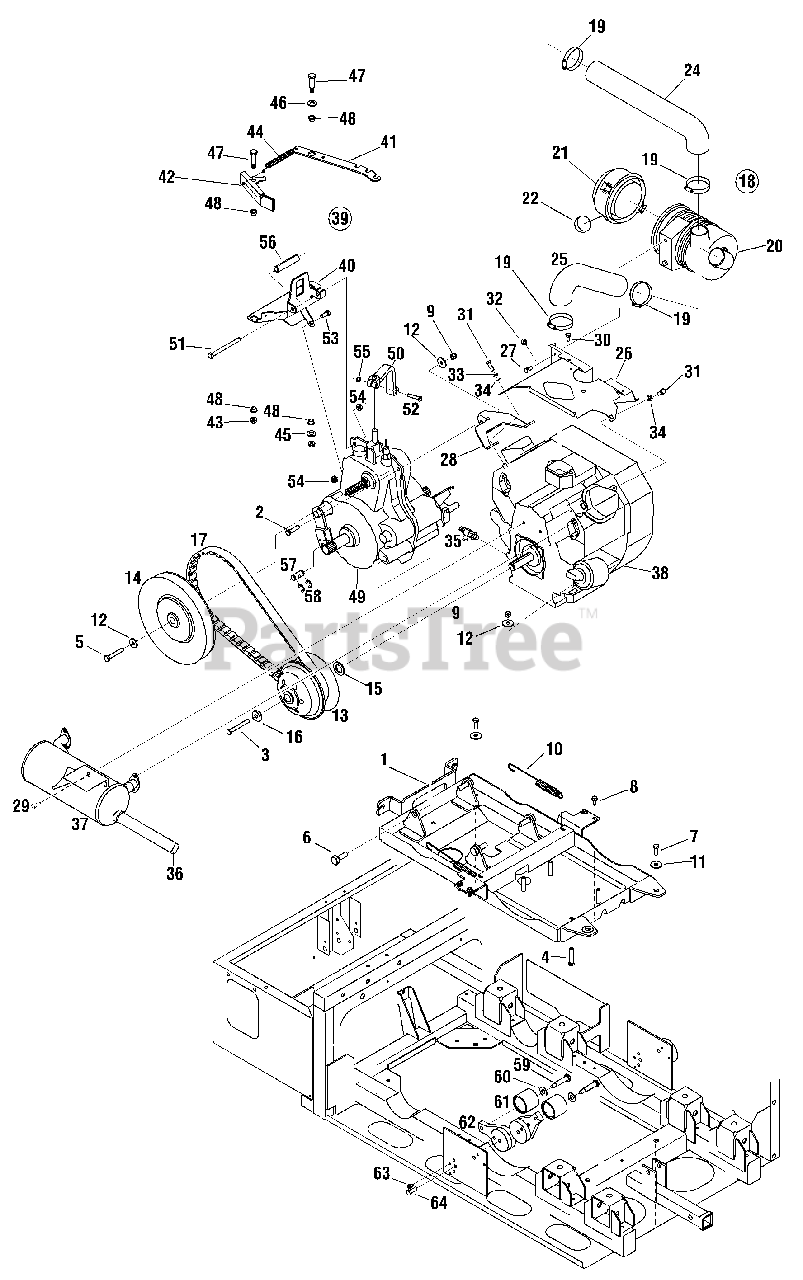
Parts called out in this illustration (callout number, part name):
1	Frame Ass'y, Engine/Trans. Support
2	Hex Screw, 3/8-16 x 1.5, Gr5
3	Hex Screw, 3/8-24 x 3, Gr5
4	Hex Screw, 3/8-16 x 2.00
5	Hex Screw, M10-1.5 x 60mm, Gr8
6	Hex Screw, M16-2 x 40mm
7	Hex Screw, 3/8-16 x 2.25, Gr5
8	Hex Screw, 5/16-18 x .75
9	Nut, Hex Lock, 3/8-16
10	Spring, Extension, .795 x 5.42
11	Washer, Flat, .411 x 1.25 x .10
12	Washer, Flat, .395 x 1.12 x .14
13	Clutch Assembly, Engine
14	Clutch Assembly, Transmission
15	Washer, 1.03 x 1.625 x .12
16	Spacer, Drive, .39 ID x 1.00 OD
17	V-type Belt, Cogged, 1.19
18	Filter Ass'y, Air Cleaner
19	Hose Clamp
20	Air Cleaner Canister
21	Air Cleaner Cap
22	Dust Ejector Valve
24	Air Intake Hose
25	Air Filter Hose
28	Support, Upper Transmission
29	Hex Screw, M8-1.25
30	Screw, Machine #10-24 x .50
31	Hex Screw, M8-1.25 x 25, Gr8
32	Grommet, Rubber.66 ID x 1.25 OD
33	Washer, Lock, 5/16
34	Washer, Flat, .33 x .678 x .030
35	Valve, Oil Drain
36	Arrestor, Spark 1-1/4
37	Muffler, Honda GXV
38	Engine, Honda GX620K1
39	Shift Ass'y, Interlock
42	Brake Clutch Lever
43	Hex Flange Lock Nut, 3/8-16
44	Extension Spring
45	Bell Washer, .375 x .870 x .063
46	Flat Washer, .510 x 1.0 x .125
47	Shoulder Screw
48	Flange Bearing
49	Transmission, Tuff Torq Model KT 35
50	Lever, Transmission
51	Hex Screw, 3/8-16 x 4.50, Gr5
52	Hex Screw, 5/16-18 x 1.50, Gr5
53	Hex Screw, 3/8-16 x .880, Gr5
54	Lock Nut, Hex Flange 3/8-16
55	Nut, Hex Lock, 5/16-18
56	Spacer, .505 x .75 x 3.31
57	Pin, .625 x 1.37
58	E-Ring, .625
59	Shoulder Screw, .50 x 1.825
60	Flat Washer, .510 x 1.12 x .060
61	Chain Roller
62	Rotary Adjuster
63	Self Tapping Screw, 1/4-20 x .50
64	Hex Screw, 3/8-16 x 1.00
